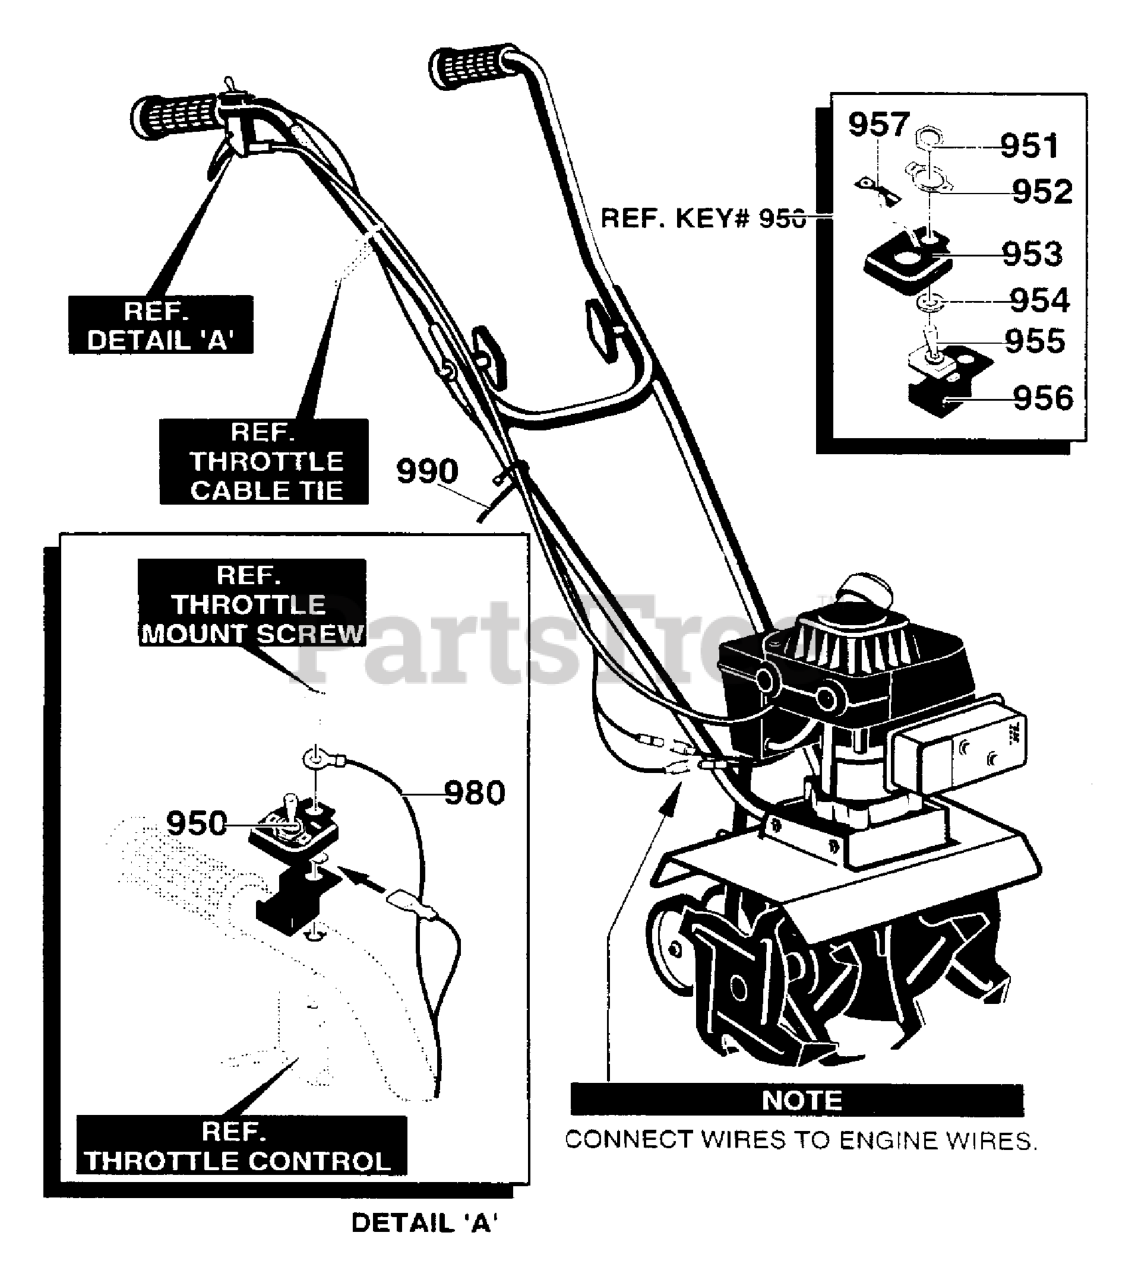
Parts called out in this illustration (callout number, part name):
950	Switch Assemby
951	Plate, Indicator
953	Bracket, Switch
954	Lockwasher
956	Bracket, Switch
957	Decal, On-Off
980	Wire Assembly, Kill Switch
990	Fastener, Cable
